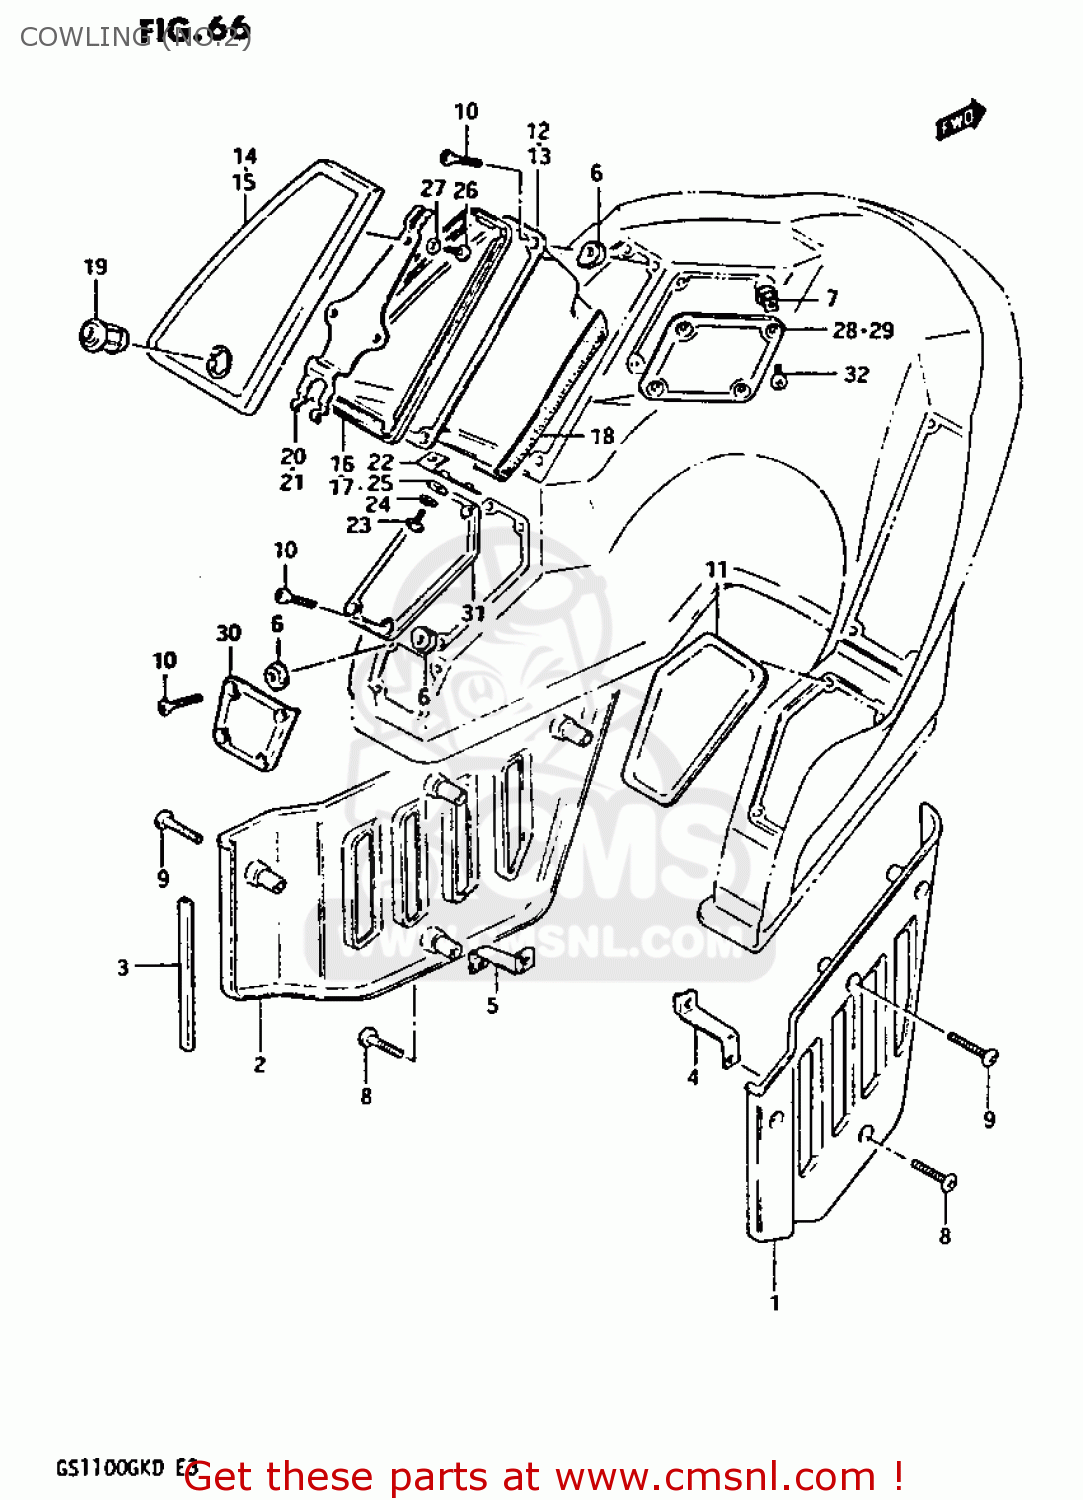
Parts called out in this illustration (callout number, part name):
1	COVER,COWLING,LOWER,RIGHT
2	COVER,LOWER,LEFT
3	MOLDING,COWLING LOWER COVER
4	BRACKET
5	BRACKET
6	PLATE,COVER FITTING NO
7	PLATE,COVER FITTING NO
8	SCREW
9	SCREW
10	SCREW (5X16)
11	GLOVE BOX,COWLING (BLACK)
12	CONSOLE BOX,RIGHT
13	CONSOLE BOX,LEFT
14	LID,CONSOLE BOX,RIGHT
15	LID,CONSOLE BOX,LEFT
16	CUSHION,CONSOLE BOX
17	CUSHION,CONSOLE BOX,LEFT
18	CUSHION CONSOLE BOX
19	LOCK,CONSOLE BOX
20	PLATE,LOCK HOLDER,RIGHT
21	PLATE,LOCK HOLDER,LEFT
22	PLATE,LOCK HOLDER SUPPORT
23	BOLT
24	WASHER,LOCK
25	WASHER
26	SCREW TAPPING
27	WASHER 4MM
28	COVER,SPEAKER,RIGHT
29	COVER,SPEAKER,LEFT
30	COVER,CB CONTROLER
31	COVER,RADIO CASE,LEFT
32	SCREW (5X30)
